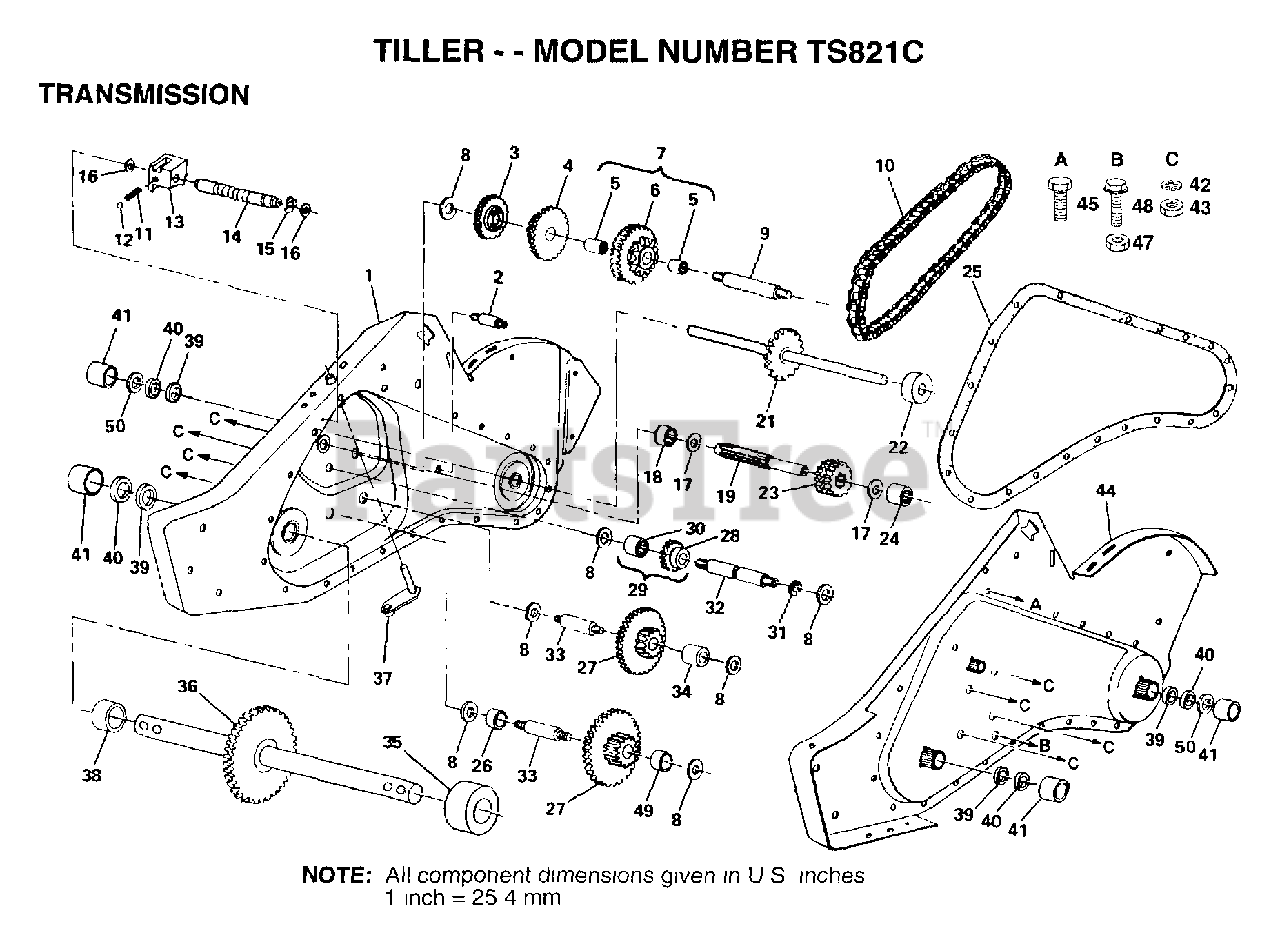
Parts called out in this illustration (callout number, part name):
2	BOLT TI
3	REVERSE GEAR TI
4	CLUSTER GEAR TI
5	"CRT, BEARING"
7	SPROCKET ASSY TI
8	WASHER
9	REDUCTION SHFT TI
10	CHAIN TI
11	SPRING-SHIFT CRT
13	SHIFT FORK TI
14	SHIFT SHAFT TI
15	KLIP RING
16	WASHER SEAL CRT
17	"T, BEARING"
18	"TI, BEARING"
19	SHAFT INPUT
21	SHAFT TINE CRT
22	SPACER CRT
23	INPUT PINION TI
24	NEEDLE BRNG LT
25	GEARCASE GSKT TI
26	SPACER CRT
27	GEAR CLUSTER CRT
28	REVERSE GEAR TI
29	GEAR ASSY TI
30	NEEDLE BEARING TI
31	KLIP RING
32	REVERSE SHAFT TI
33	SHAFT CRT
34	SPACER CRT
35	SPACER CRT
36	SHAFT ASSY CRT
37	BRACKET ASM SHIFT
38	SPACER CRT
39	OIL SEAL STD
40	SEAL RING RUBBER
41	CUP.FORMED.
42	LOCKWASHER
43	NUT.ASF.HEX.7/16
45	SCREW 5/16-18X5/8
47	NUT.HEX.5/16-18
48	BOLT TI
49	SPACER CRT
50	RING SPIRAL CRT
